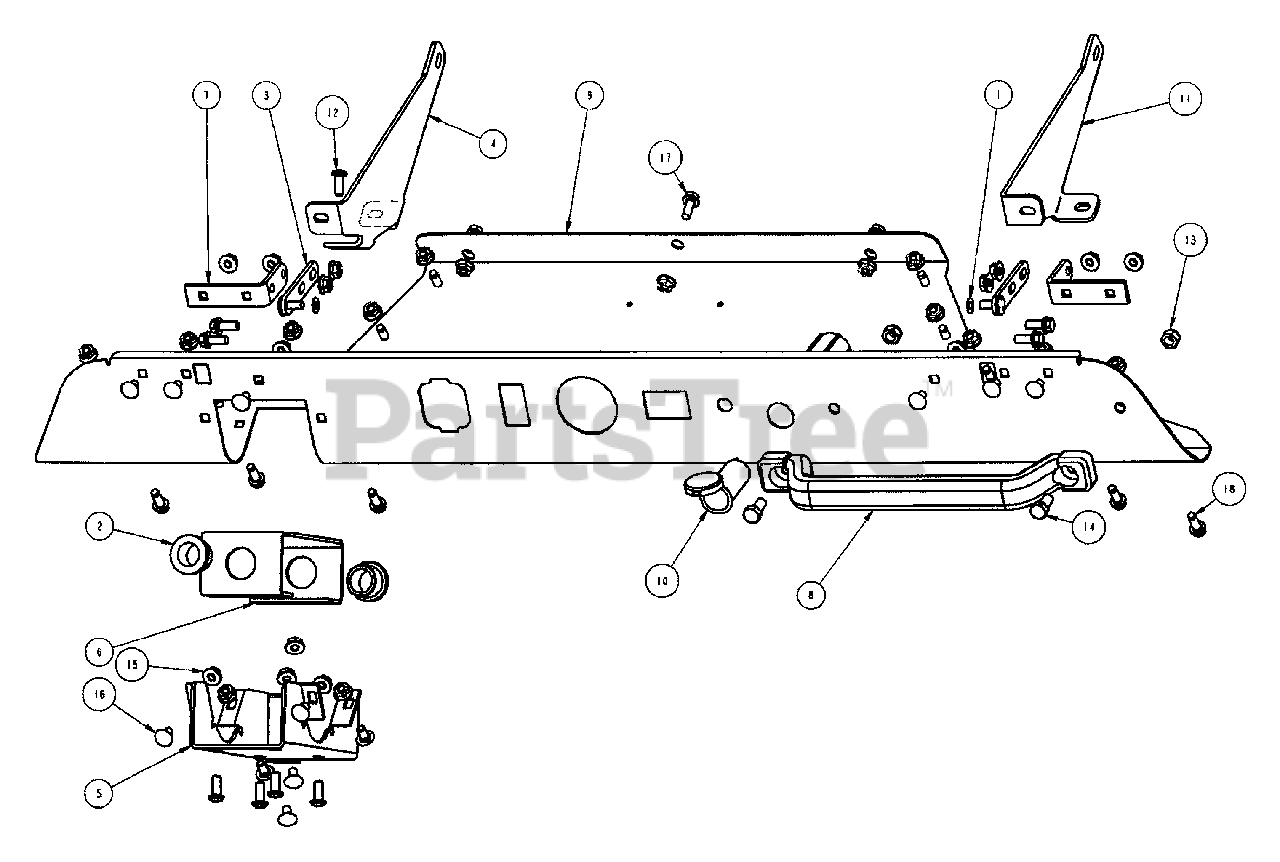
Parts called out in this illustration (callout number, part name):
1	BOLT RET, 1/4
2	BEARING, .750 ID
3	WELDMENT, HOOD HINGE
4	SUPPORT, DASH
5	STEERING SUPPORT, OUTER
6	STEERING, SUPPORT, INNER
7	HINGE LOWER
8	HANDLE
9	DASH, CVT UTILITY VEHICLE
10	12 VOLT DC POWER OUTLET
11	DASH BRACE, RH
12	PHST, 1/4-20 X 5/8 TORX
13	HEX NYLON INSERT NUT 5/16-18 YZ
14	HHCS, 5/16-18 X 3/4 YZ
15	HFLN, 1/4-20
16	RHSSNB, 1/4-20 X 1/2 YZ
17	HFLS, 1/4-20 X 5/8
18	HWST, 1/4-20 X 1/2 YZ
